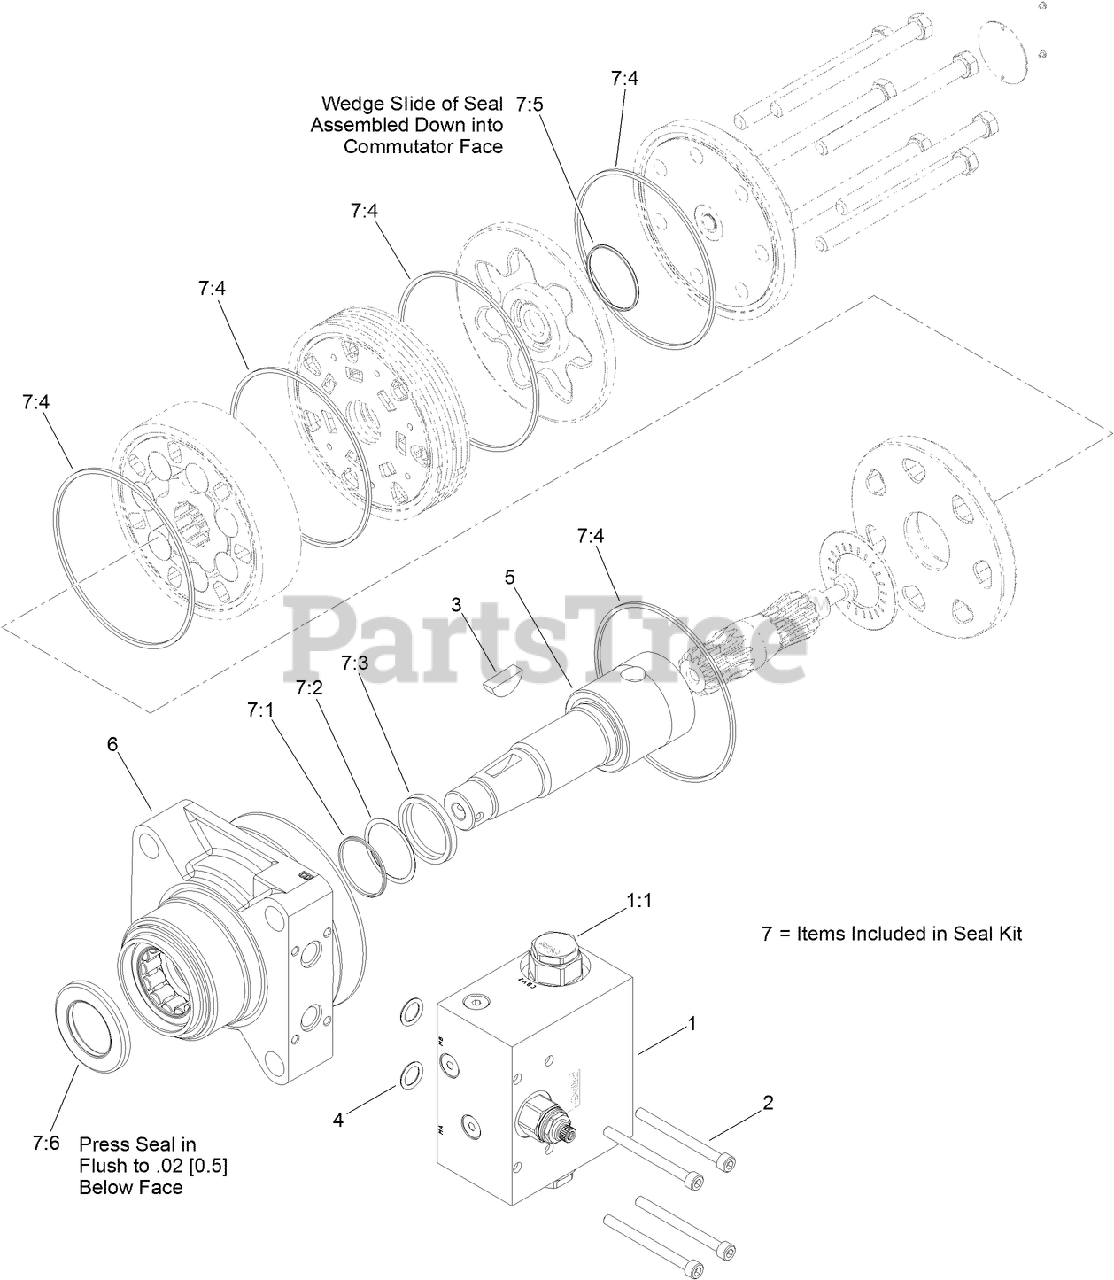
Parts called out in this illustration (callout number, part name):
1	COUNTERBALANCE VALVE ASM
1:1	VALVE-CARTRIDGE
2	BOLT-HSH
3	KEY-WOODRUFF
4	O-RING
5	SHAFT-COUPLING
6	MOTOR HOUSING ASM
7:1	Ring-Back Up
7:2	Washer-Back Up
7:3	SEAL-Shaft
7:4	Deck ASM
7:5	Deck ASM
7:6	Deck ASM
